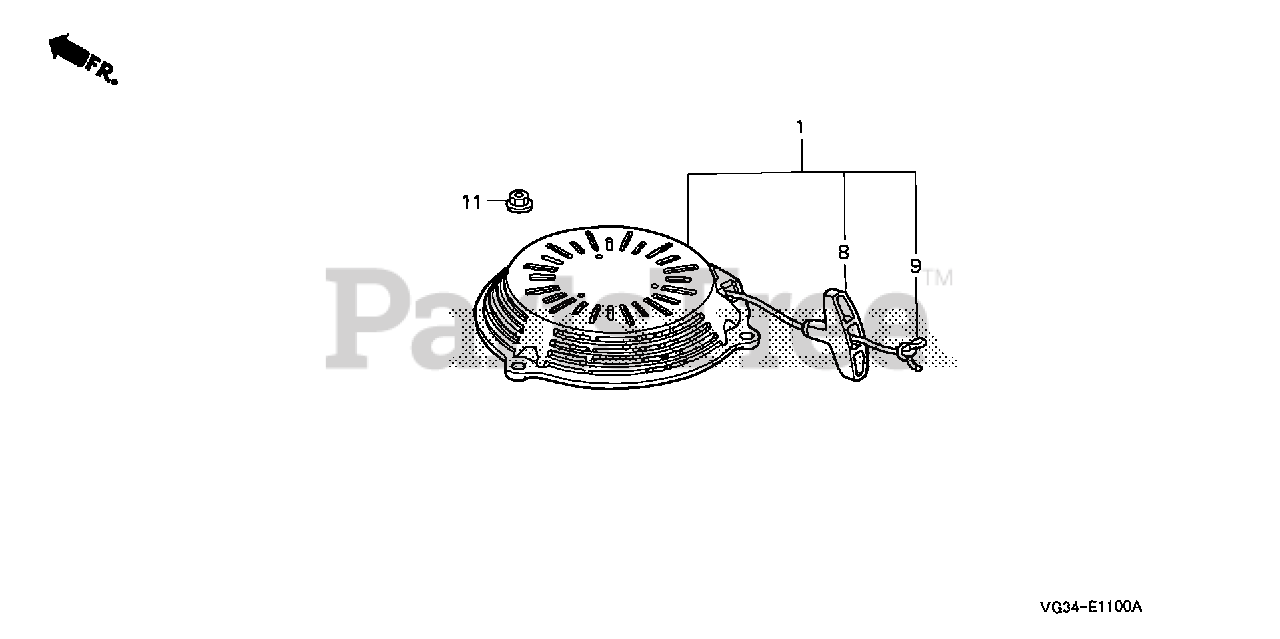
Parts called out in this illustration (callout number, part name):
1	STARTER ASSY., RECOIL *R280* (LONG ROPE) (POWER RED)
8	GRIP, STARTER
9	ROPE, RECOIL STARTER (LONG TYPE)
11	NUT, FLANGE (6MM)
